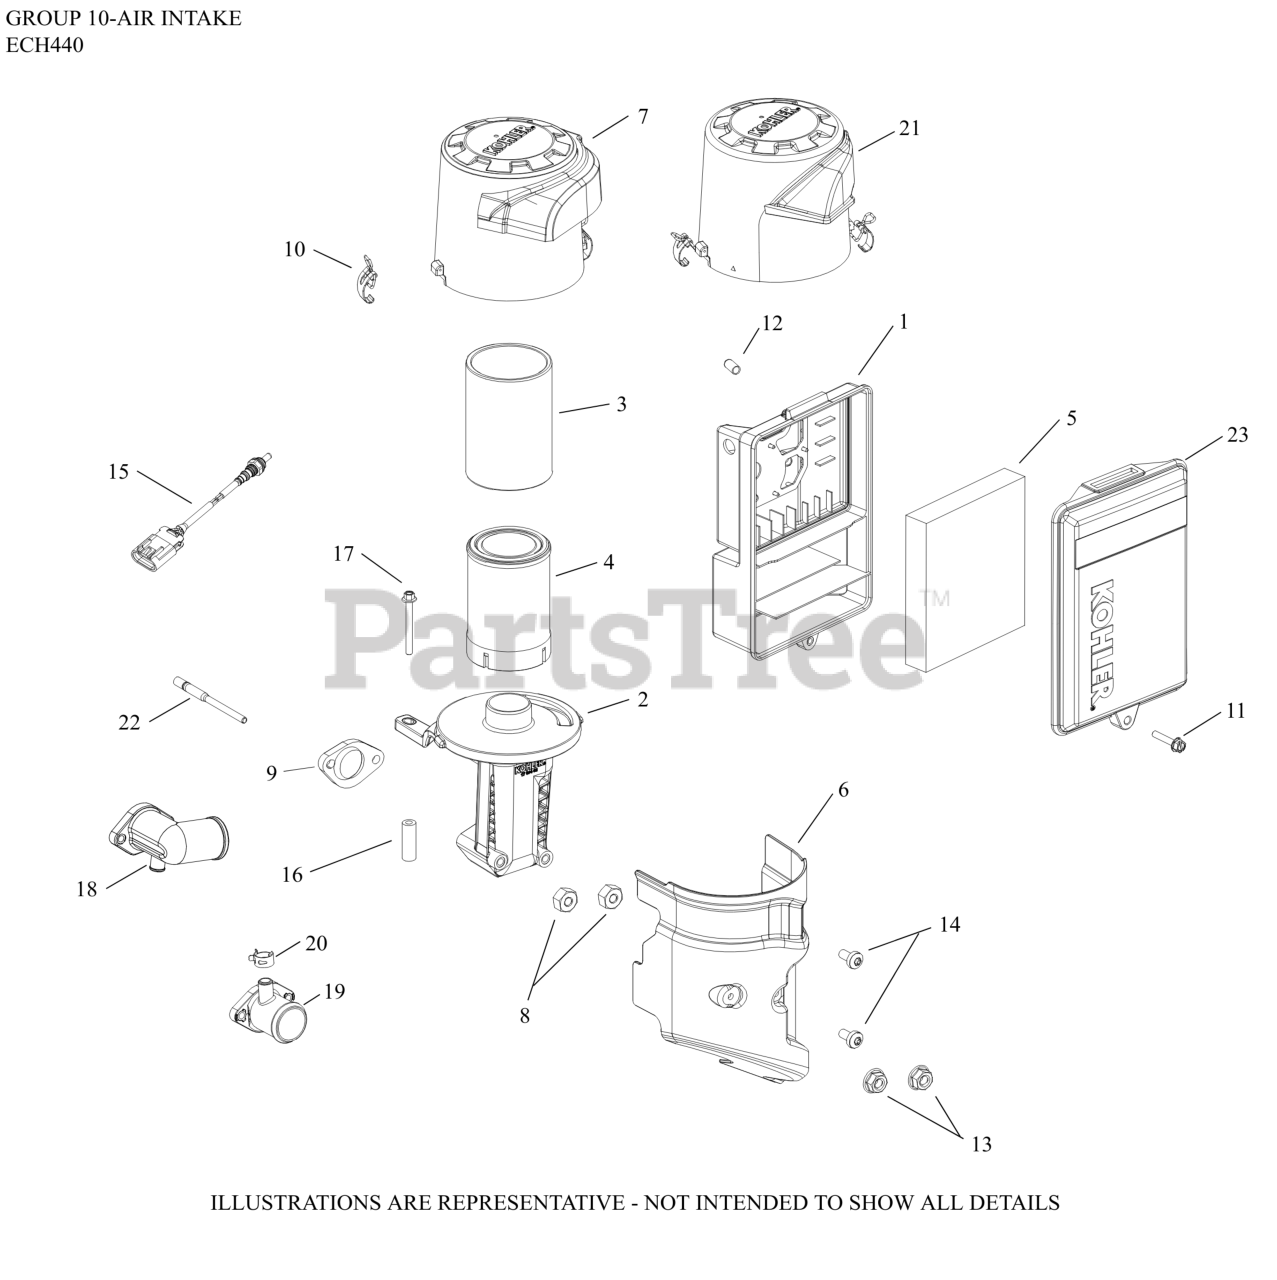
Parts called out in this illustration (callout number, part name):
9	INSULATOR THROTTLE BODY
13	NUT, HEX FLANGE LOCK (M6)
18	ELBOW, AIR INLET
20	CLAMP, BREATHER HOSE
